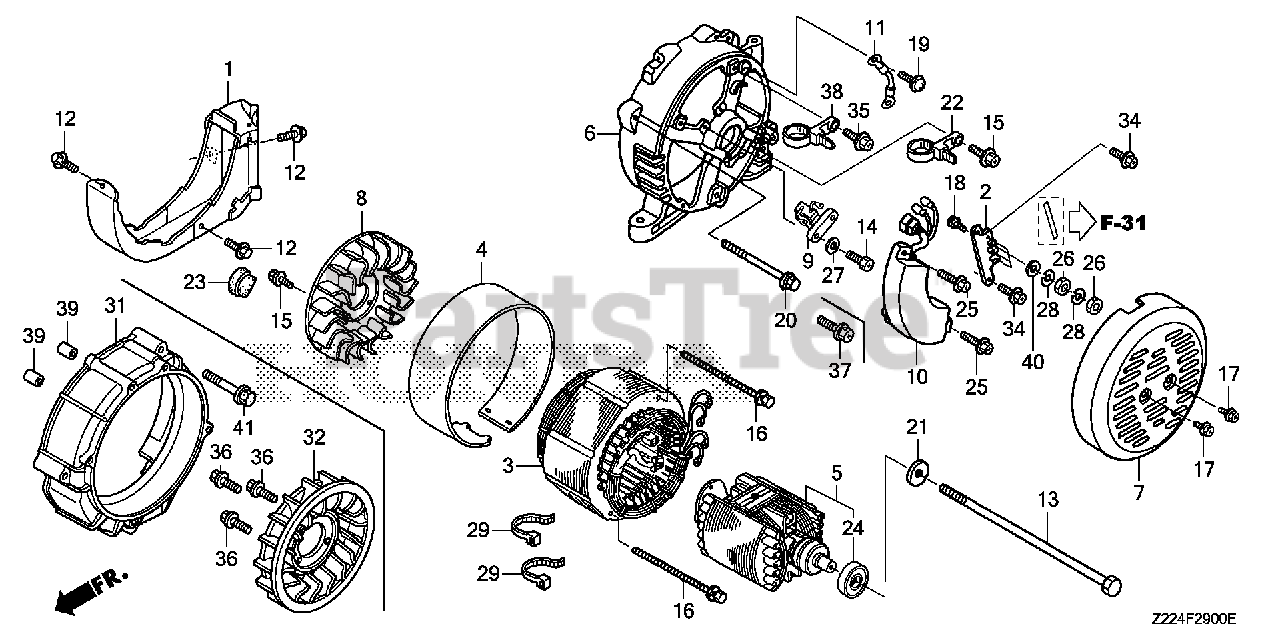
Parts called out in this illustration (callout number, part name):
2	TERMINAL, VOLT CHANGE
3	STATOR ASSY.
4	COVER, STATOR *NH105* (MAT BLACK)
6	HOUSING, RR.
7	COVER, GENERATOR END *NH105* (MAT BLACK)
9	BRUSH ASSY.
11	WIRE, GROUND
13	BOLT, HEX. (10X237)
17	SCREW, TAPPING (5X12)
18	BOLT, HEX. (5X20)
19	SCREW, PAN (5X12)
20	BOLT, FLANGE (6X147)
21	WASHER (10.5MM)
24	BEARING ASSY. (6204)
26	NUT, HEX. (5MM)
28	WASHER, SPRING (5MM)
31	HOUSING, FR.
32	FAN, GENERATOR COOLING
34	SCREW, TAPPING (5X14)
35	SCREW, TAPPING (5X14)
36	SCREW, TAPPING (5X14)
37	SCREW, TAPPING (5X18)
38	TIE, CABLE
39	PIN, DOWEL (8X12)
40	WASHER, PLAIN (5MM)
41	BOLT, FLANGE (8X60)
